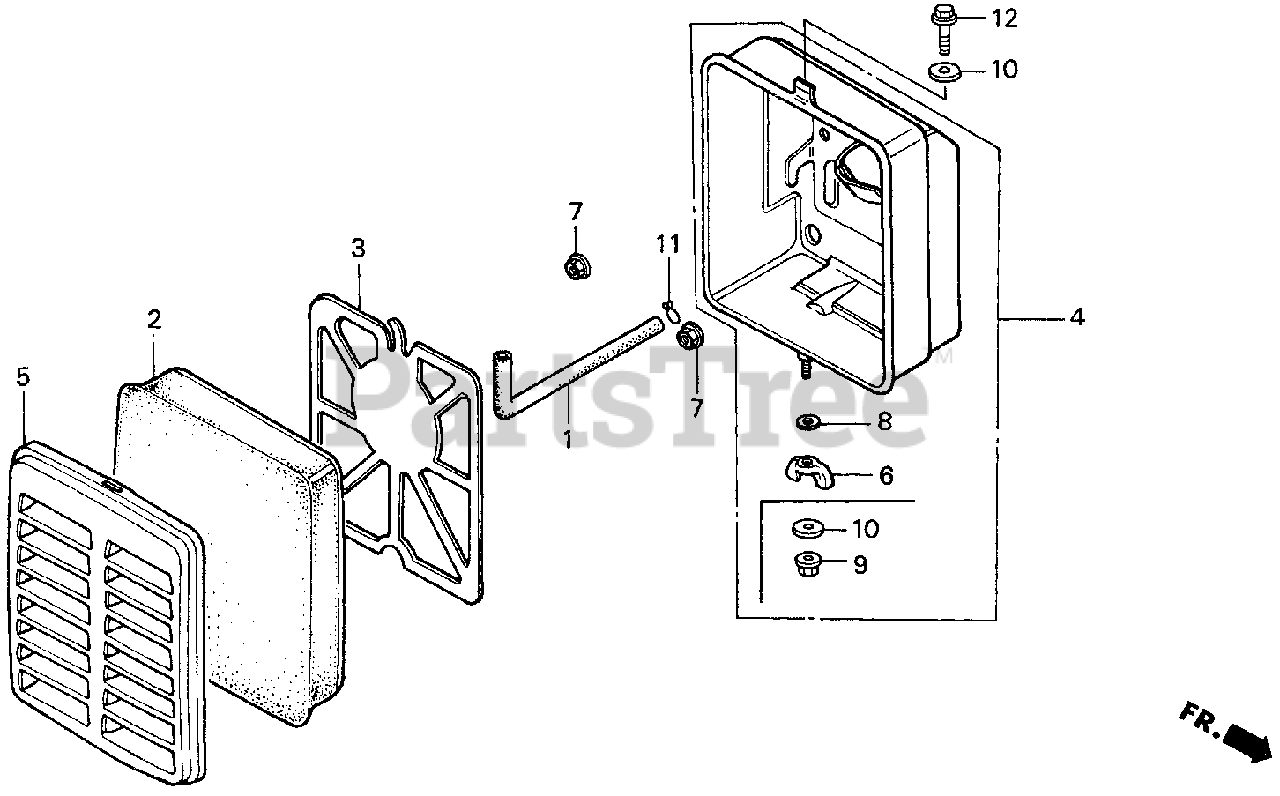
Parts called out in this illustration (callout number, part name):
1	TUBE, BREATHER
2	ELEMENT, AIR CLEANER
3	GRID, AIR CLEANER
4	HOUSING, AIR CLEANER
5	COVER, AIR CLEANER
6	WINGNUT, TOOL BOX SETTING
7	NUT, FLANGE (5MM)
8	WASHER, PLAIN (6MM)
